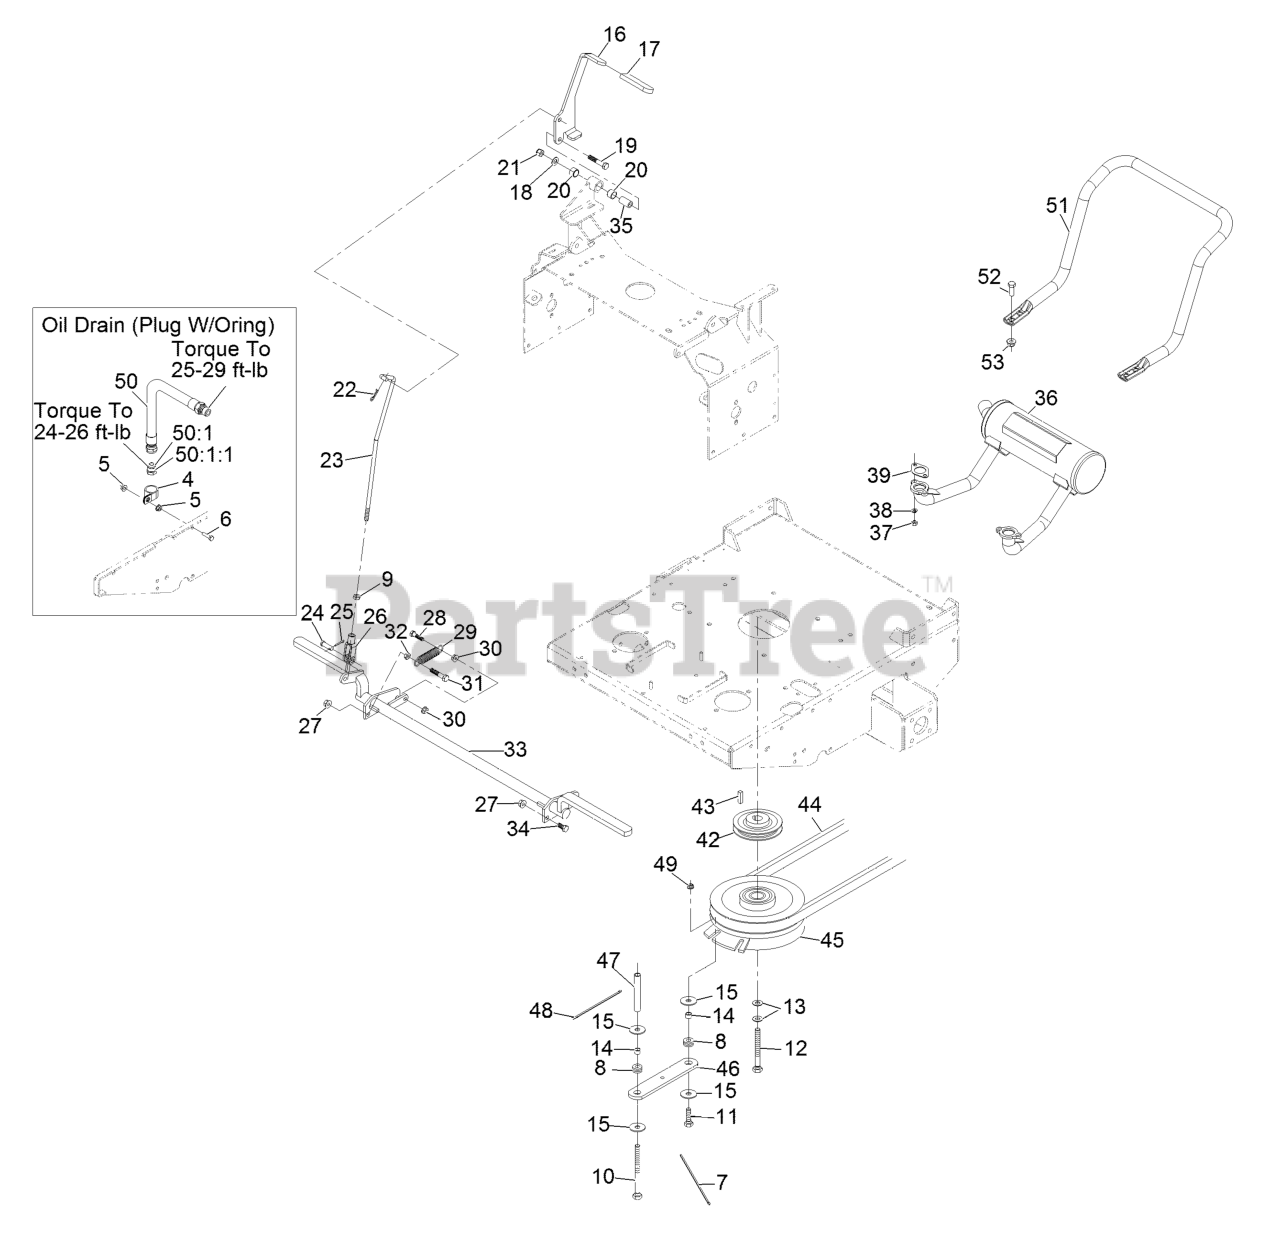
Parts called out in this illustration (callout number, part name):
4	CLIP-LOOM
6	SCREW-HH
7	TIE-PLASTIC
8	GROMMET
9	NUT-HJ
10	SCREW-HH
11	SCREW-HH
12	SCREW-HH
13	WASHER-SPRING
16	LEVER,PRK BRK W/DECALS
17	GRIP-LEVER
18	WASHER-FLAT
19	SCREW-HH
20	SLEEVE-BUSHING
21	NUT-LOCK, NI
22	PIN-COTTER
23	LINKAGE, PARK BRAKE
24	PIN-CLEVIS
25	PIN-COTTER
26	YOKE-LINKAGE, BRAKE
27	NUT-HHF, WHIZ
28	SCREW-HH, SPECIAL
29	SPRING-IDLER
31	SCREW-HH
32	NUT-JAM
33	WLD,BRAKE TTX
34	SCREW-HH
35	BUSHING-PIVOT
36	MUFFLER,HORIZONTAL
38	WASHER-LOCK
39	GASKET-EXHAUST
42	PULLEY
44	BELT,DECK DRIVE
45	CLUTCH ASM
46	STRAP-CLUTCH, BRAKE
47	SPACER,SHIELD
48	TIE-CABLE
50	ENGINE OIL DRAIN HOSE ASM
50:1	PLUG-HH
50:1:1	O-RING
51	GUARD-MUFFLER
52	SCREW-HH
53	NUT-HF, NI
